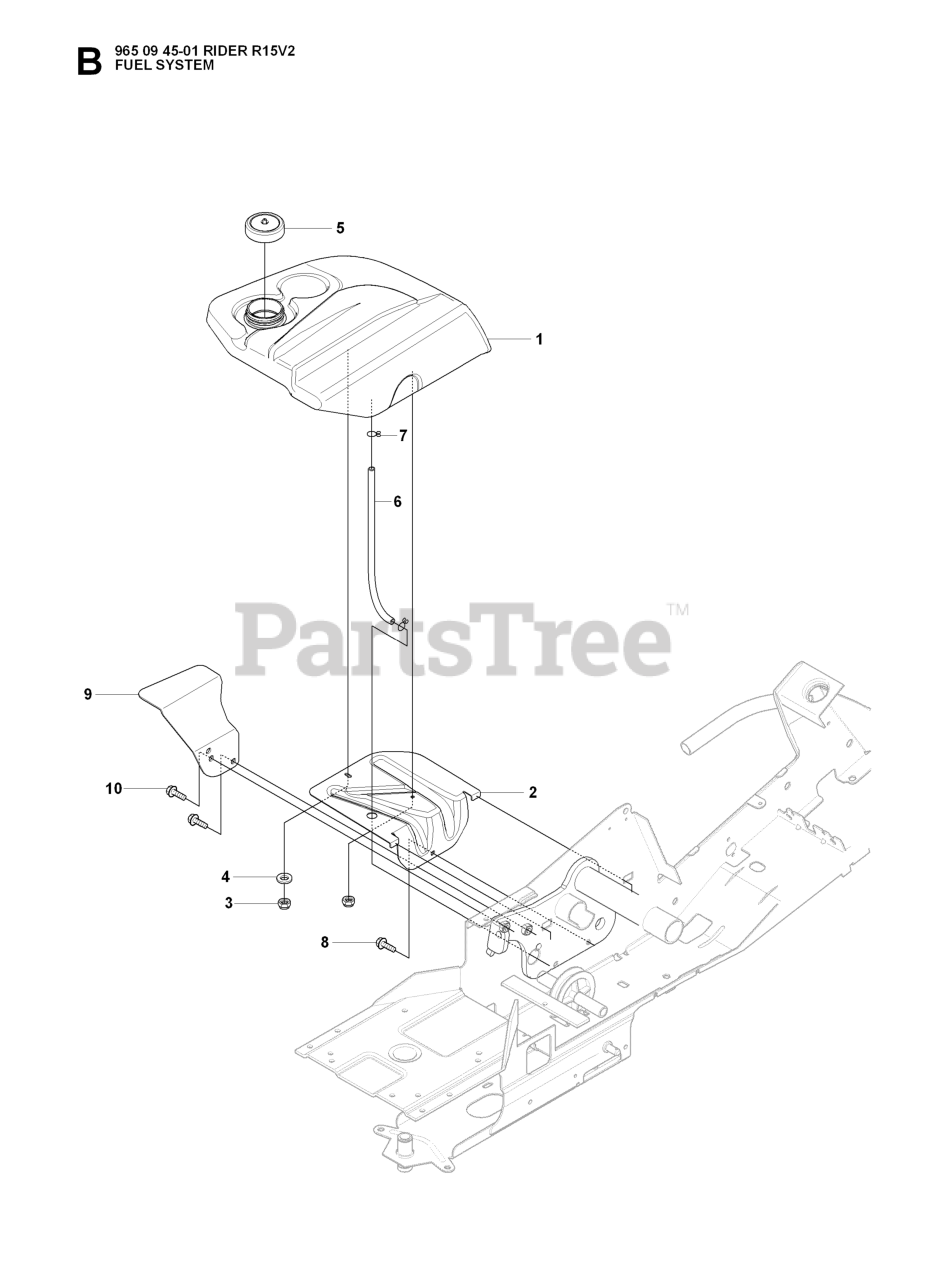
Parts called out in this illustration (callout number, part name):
3	LOCKNUT M6
4	WASHER
10	Screw M10x25
